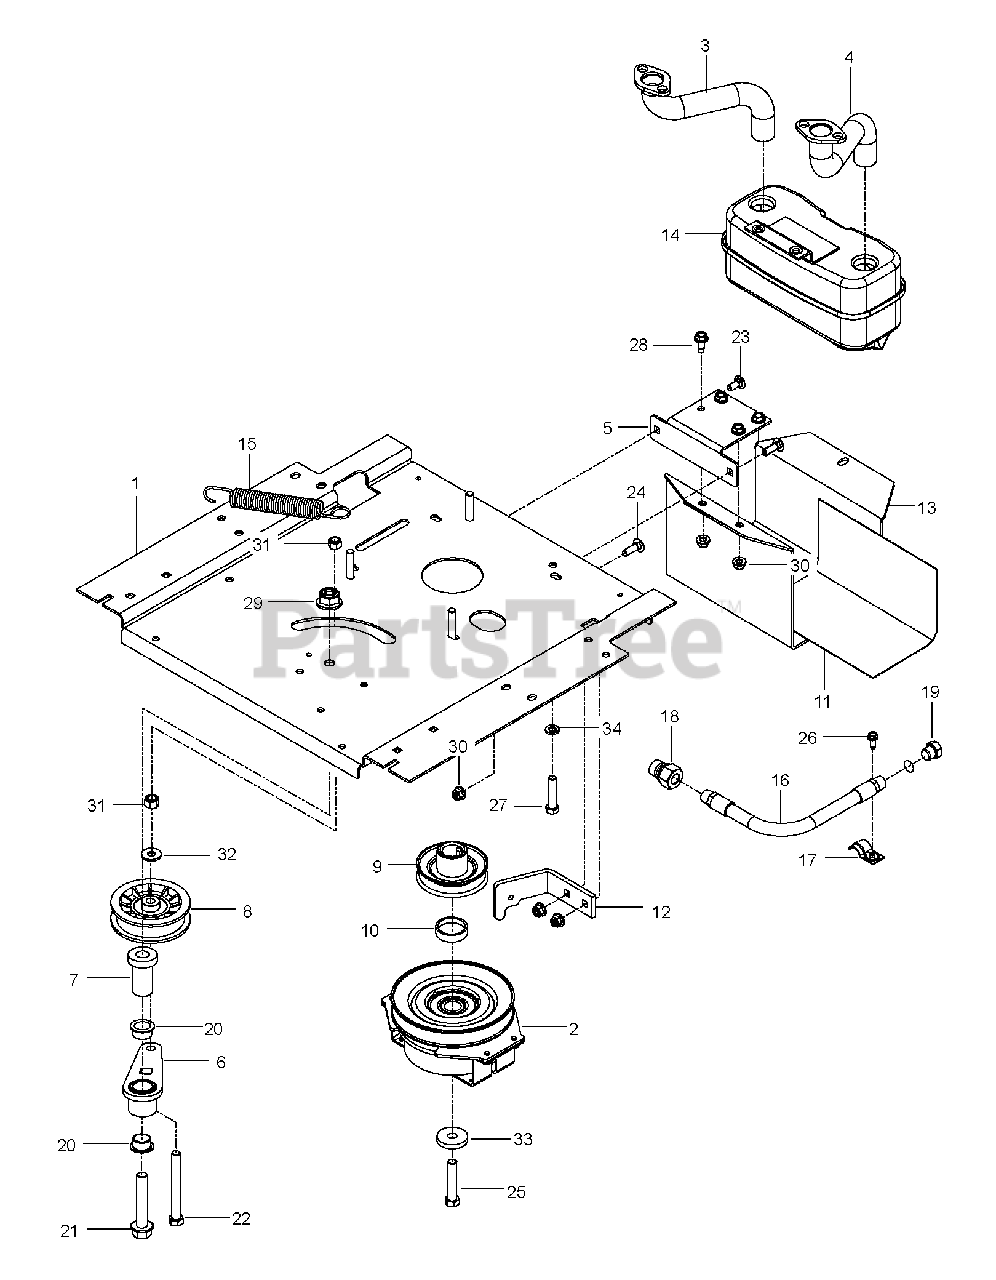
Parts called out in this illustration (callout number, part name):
1	PLATE.ENGINE.PNT.23"FRAME.EDIP
2	CLUTCH.OGURA.5.0PD.GT1.5A-EH07
3	TUBE.EXHAUST.RH.FR961/FR730
4	TUBE.EXHAUST.LH.FR961/FR730
5	BRACKET MUFFLER MS431BLK
6	ARM IDLER
7	SPINDLE.IDLER
8	PULLEY, IDLER RAKE & ZTR
9	PULLEY.ENGINE
10	SPACER.SPACER.625 W/OGURA.LCC
11	HEAT SHIELD
12	CLUTCH.STOP.OGURA LCC.BLACK
13	GUARD.MUFFLER.WO.TOW.HITCHX431
14	MUFFLER ASM TWIN
15	SPRING, DECK DRIVE
16	HOSE.ASSEMBLY.OIL.DRAIN
18	BOLT.FLANGE.1/2-13 X 2.75.GRD5
19	HCS 3/8-16X3-1/2 TAPBLT GR5 ZD
20	BEARING.FLANGED.PLASTIC.3/4ID
21	BOLT.FLANGE.1/2-13 X 2.75.GRD5
22	HCS 3/8-16X3-1/2 TAPBLT GR5 ZD
23	BOLT 5/16-18 X3/4 ZN/YEL GR 5
25	CLUTCH BOLT7/16-20X2.5 GR524HR
26	SCR 1/4-20X5/8 HEX SELF TAP ZD
27	BOLT, HCS 3/8-16X1-3/4
28	SCREW
29	NUT, 1/2-13 HEX FLG NYLOC ZD
30	5/16-18 NYLOC FLANGE NUT
31	NUT 3/8-16 NYLOC
32	WASHER
34	LOCKWASHER
